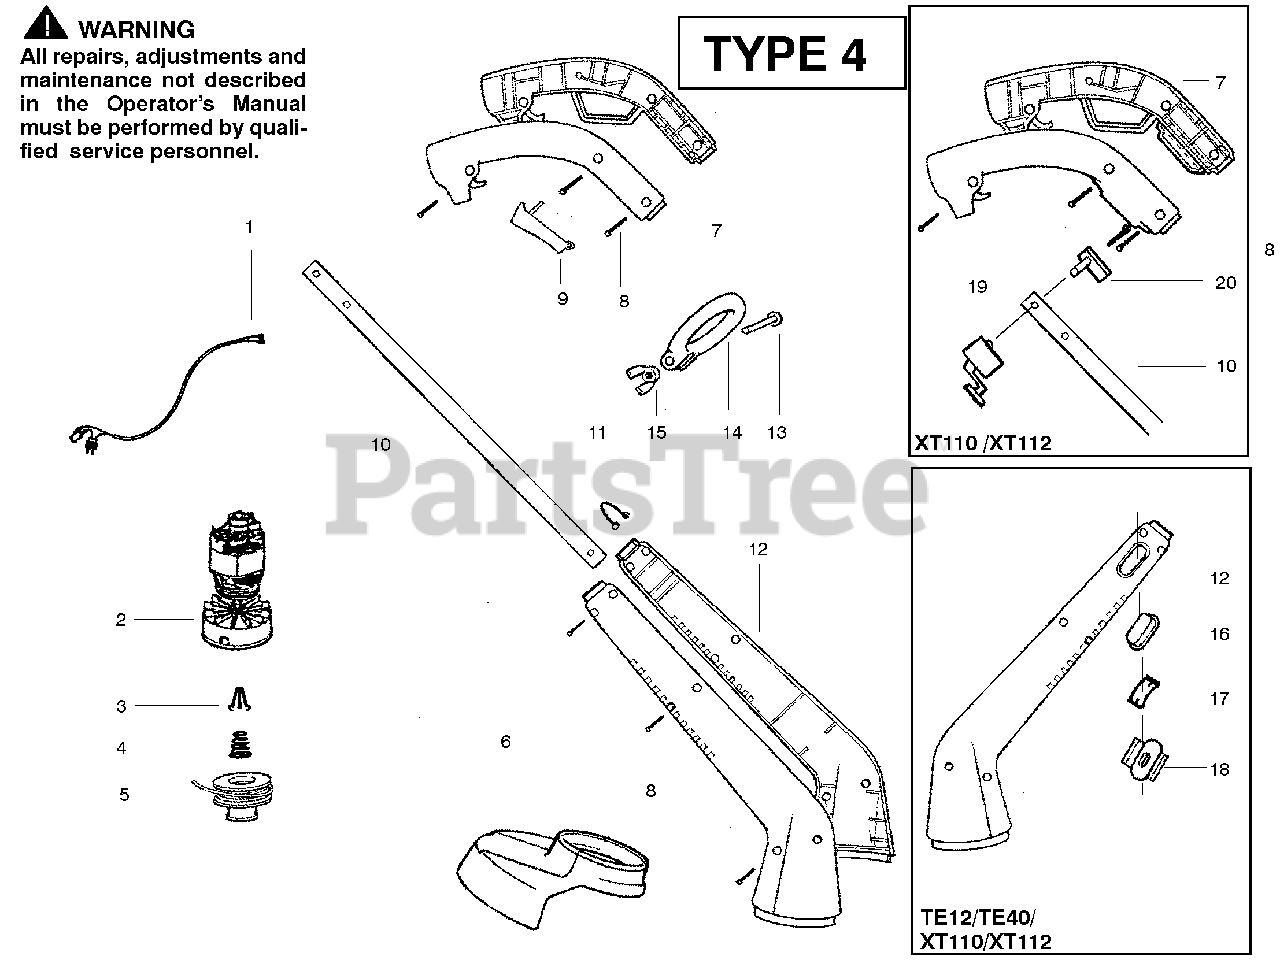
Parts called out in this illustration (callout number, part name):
3	Retainer-Spool
4	Spring-Return
5	Spool w/ Line
11	Snap Button
15	Wing Nut
